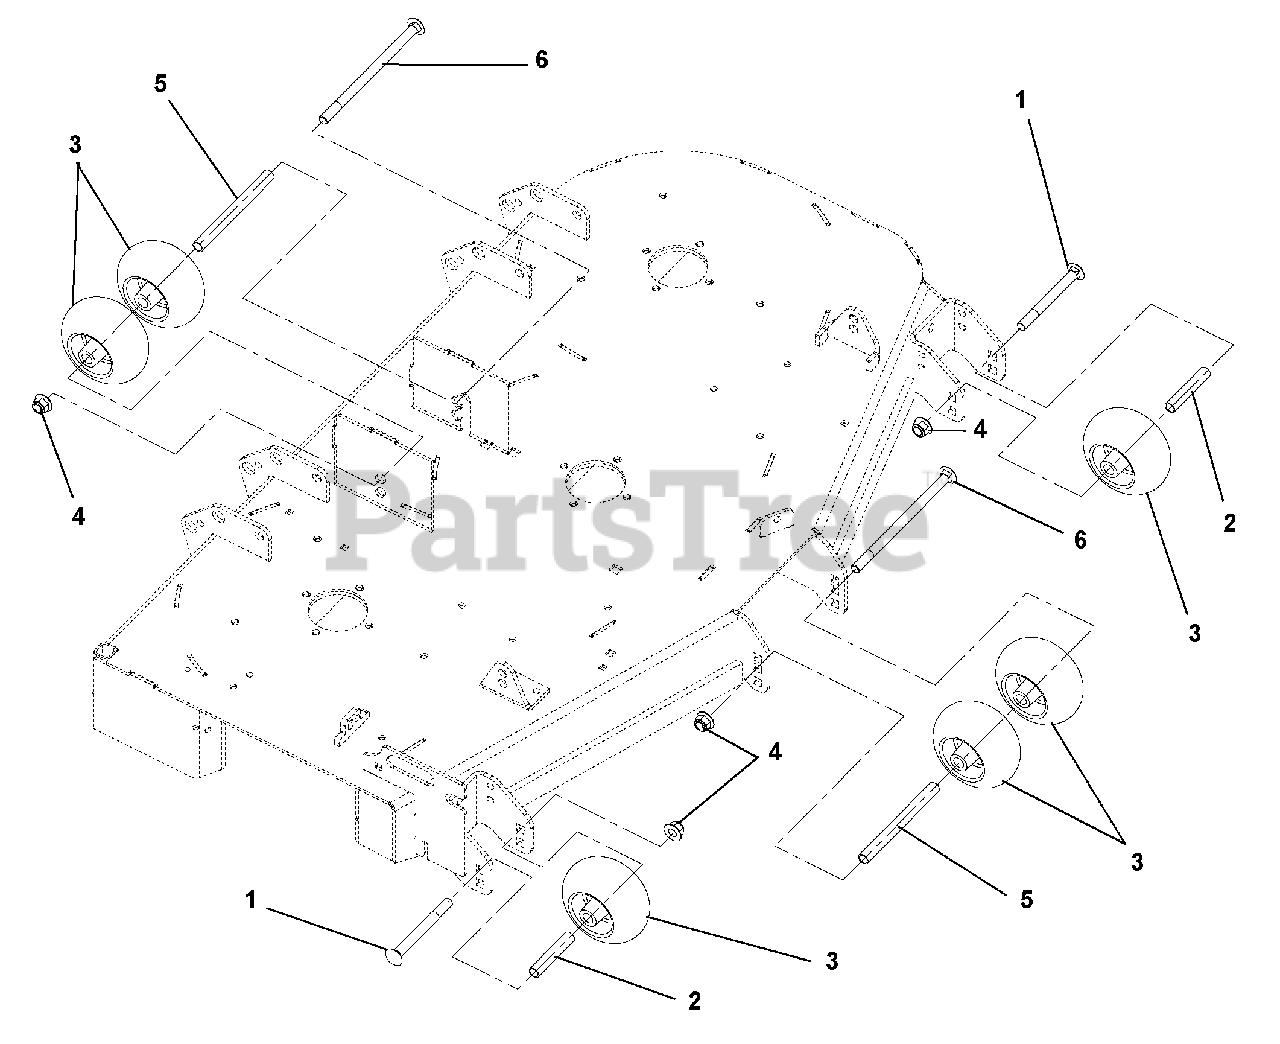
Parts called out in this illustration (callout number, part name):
1	Bolt, Round Head Square Neck .50-13 x 5.00
2	Spacer, .510 x .625 x 3.35
3	Anti-Scalp Wheel
4	Nut, .50-13 Nyloc Flange
6	Bolt, Round Head Square Neck .50-13 x 8.50
